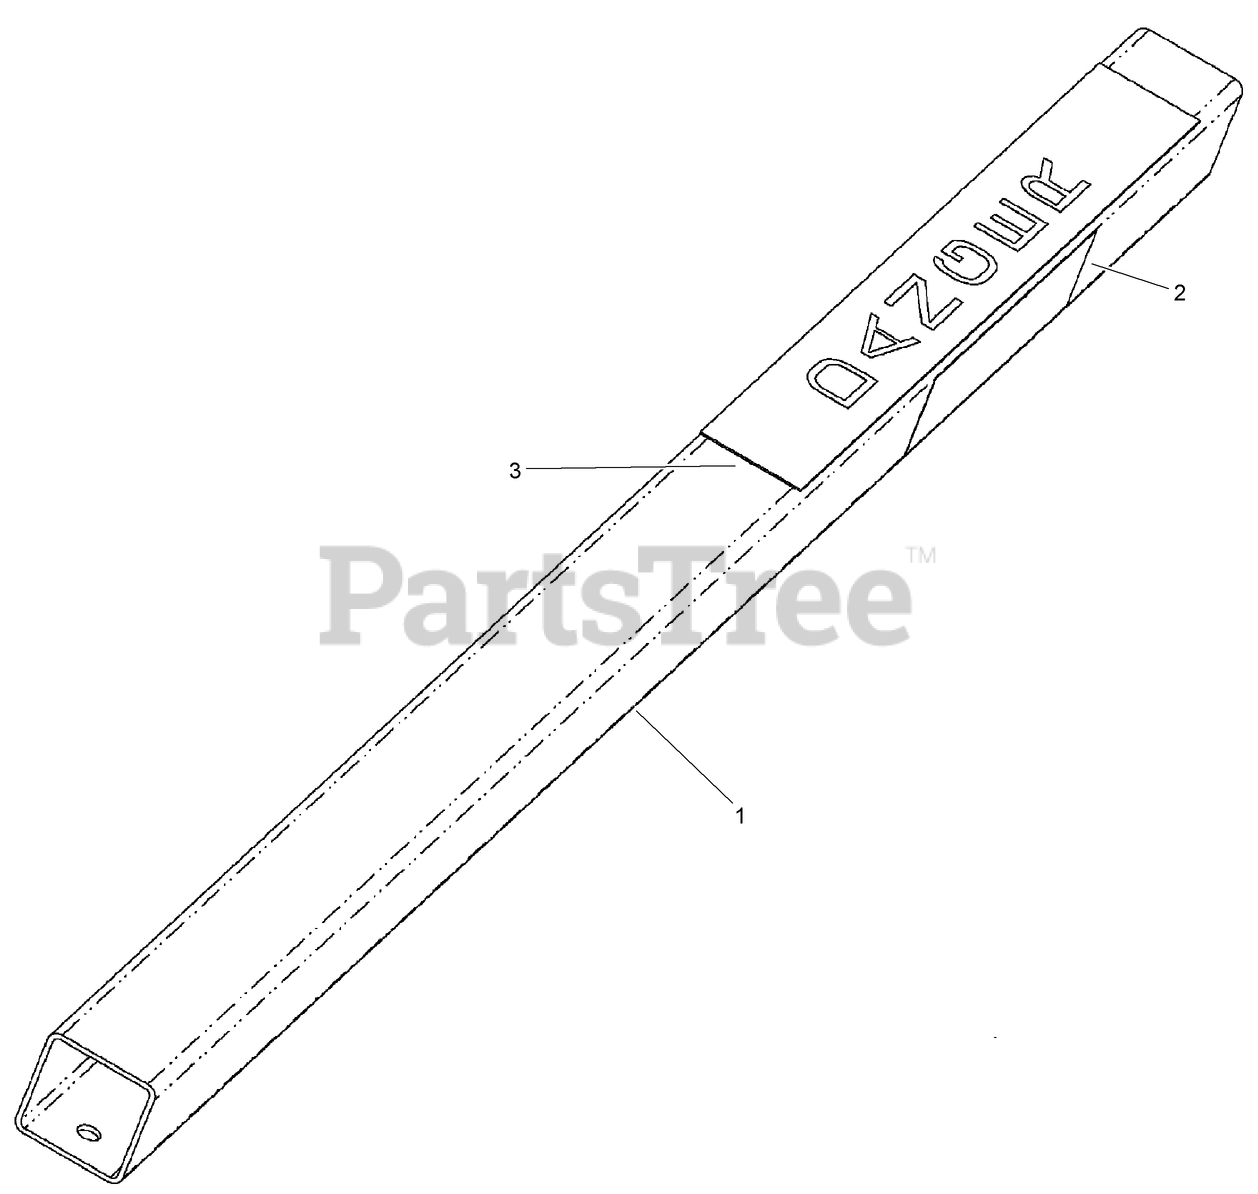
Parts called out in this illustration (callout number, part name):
1	TUBE-Restraint Bar
2	DECAL-Danger, Entanglement Hazard
3	DECAL-Danger
